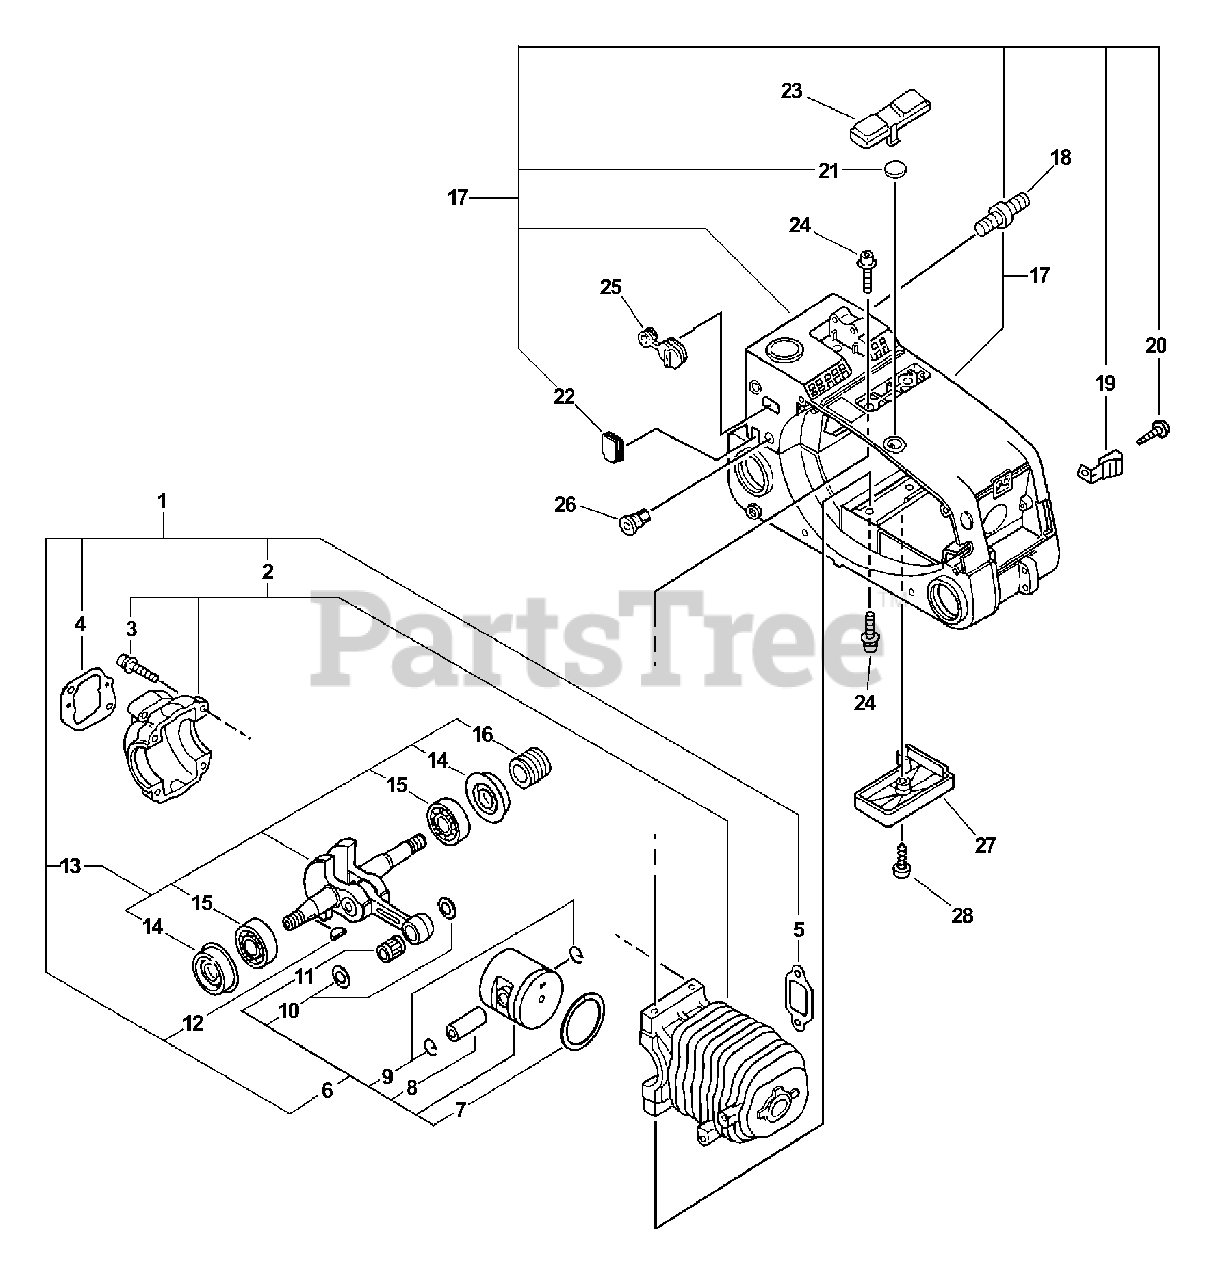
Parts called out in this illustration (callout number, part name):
1	SHORT BLOCK CS-3000
2	CRANKCASE SET
3	SCREW 5×25
4	GASKET, INTAKE
5	GASKET, MUFFLER
6	PISTON KIT
7	RING, PISTON
8	PIN, PISTON
9	RING, SNAP
10	WASHER, THRUST
11	BEARING, NEEDLE 8
12	KEY, WOODRUFF
13	CRANKSHAFT ASSY
14	SEAL, OIL
15	BEARING, BALL - 6201 C3
16	GEAR, WORM
17	ENGINE COVER KIT
17	COVER, ENGINE
18	BOLT, STUD 6
19	LATCH
20	SCREW 4×10
21	PLUG
22	PLUG
23	PLUG
24	BOLT 5×16
25	GROMMET
25	GROMMET, CHOKE
26	GROMMET, IDLE
27	PLUG
28	SCREW 4×16
